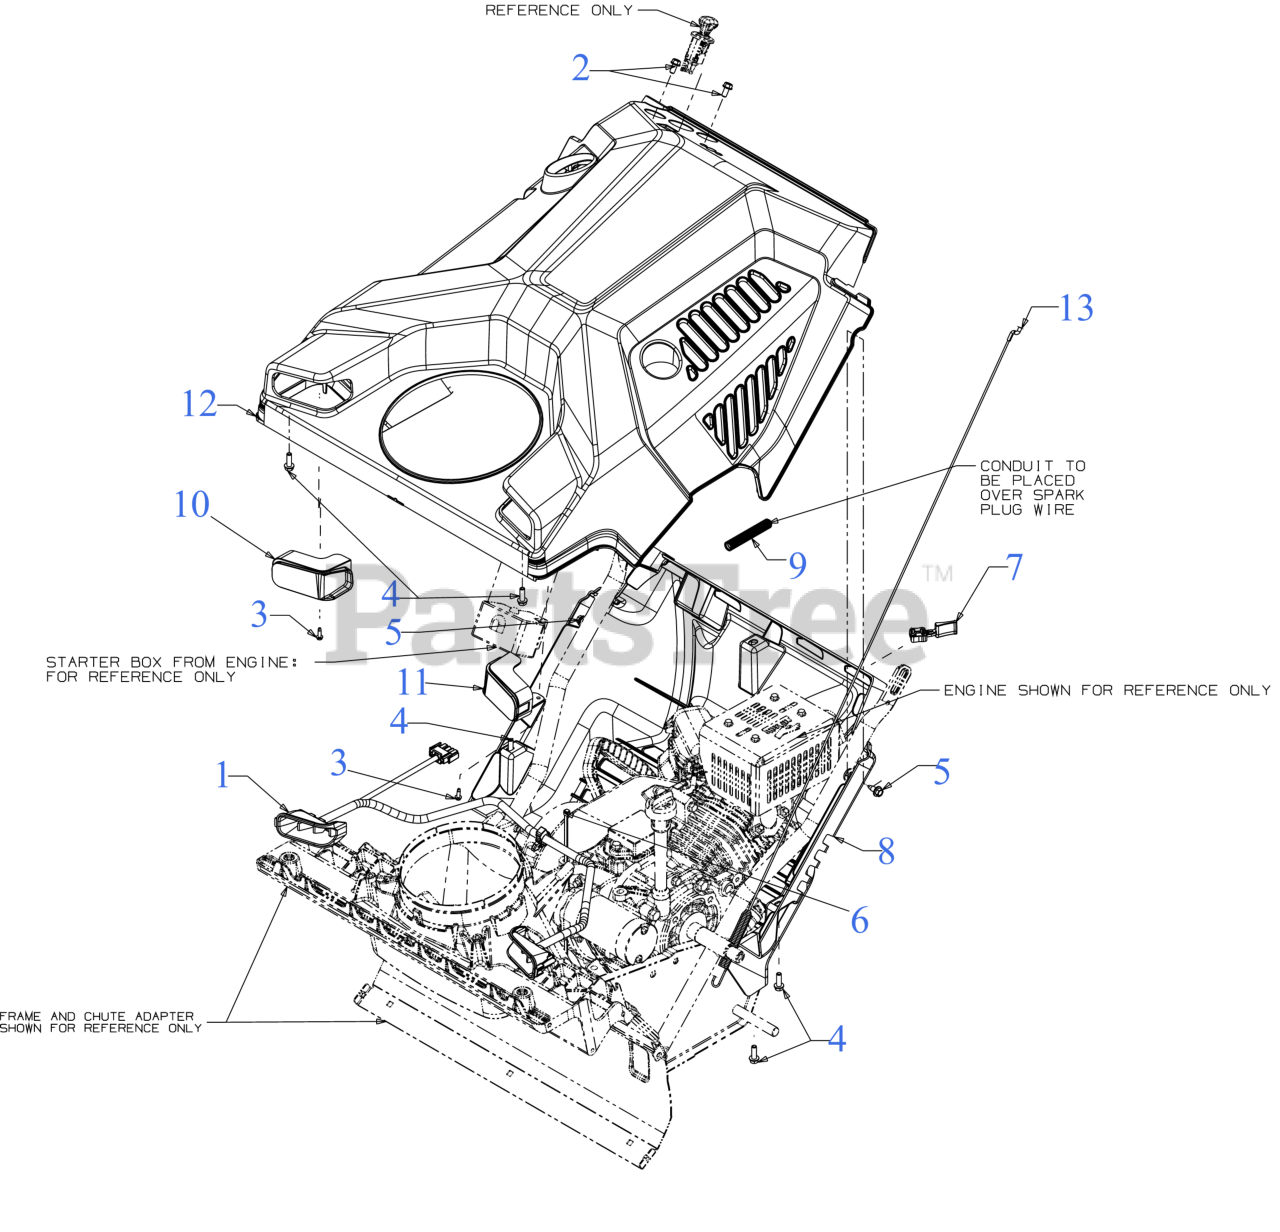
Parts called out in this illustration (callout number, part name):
1	LED HEADLIGHT HARNESS ASSEMBLY
2	HEX SCREW 1/4-15 x .50
3	SCREW #8-16 x .50
4	SCREW 1/4-15 x .750
5	SCREW 1/4-20X.625
6	CABLE TIE
7	CHOKE EXTENION LEVER
8	BOTTOM COVER
9	CONVOLUTED CONDUIT
10	LED LENS (RH)
11	LED LENS (LH)
12	TOP COVER (H STY-YLW W/HDLT)
13	AUGER CLUTCH CABLE 37.05"
